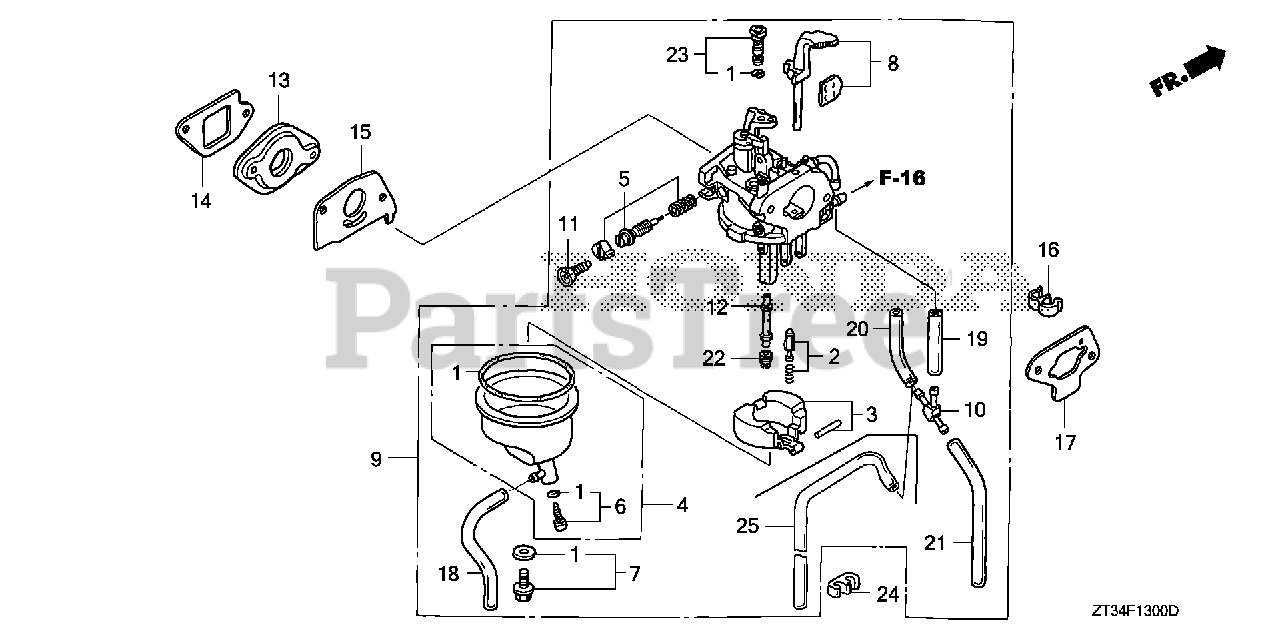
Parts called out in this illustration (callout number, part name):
1	GASKET SET
2	VALVE SET, FLOAT (SEAT NOT INCLUDED)
4	CHAMBER SET, FLOAT
5	SCREW SET, PILOT
6	SCREW SET, DRAIN
7	SCREW SET
9	CARBURETOR ASSY. (BF30D C)
9	CARBURETOR ASSY. (BF30D C/D)
10	JOINT, AIR VENT TUBE
11	SCREW, THROTTLE STOP
12	NOZZLE, MAIN
13	INSULATOR, CARBURETOR
14	GASKET, INSULATOR (ENGINE NO.)
15	GASKET, CARBURETOR
16	CLAMP, TUBE (7.5X2)
17	GASKET, AIR IN. JOINT
18	BULK HOSE, VINYL (3.5X6.5X8000) (3.5X6.5X190)
19	BULK HOSE, VINYL (4X7X8000) (4X7X50)
20	BULK HOSE, VINYL (4X7X8000) (4X7X70) (FRAME NO.)
21	BULK HOSE, VINYL (4X7X8000) (4X7X160)
22	JET, MAIN (#52)
22	JET, MAIN (#55)
22	JET, MAIN (#58)
23	JET SET, PILOT (#35)
24	CLAMP D, IGNITION WIRE
25	BULK HOSE, VINYL (4X7X8000) (4X7X350) (FRAME NO.)
